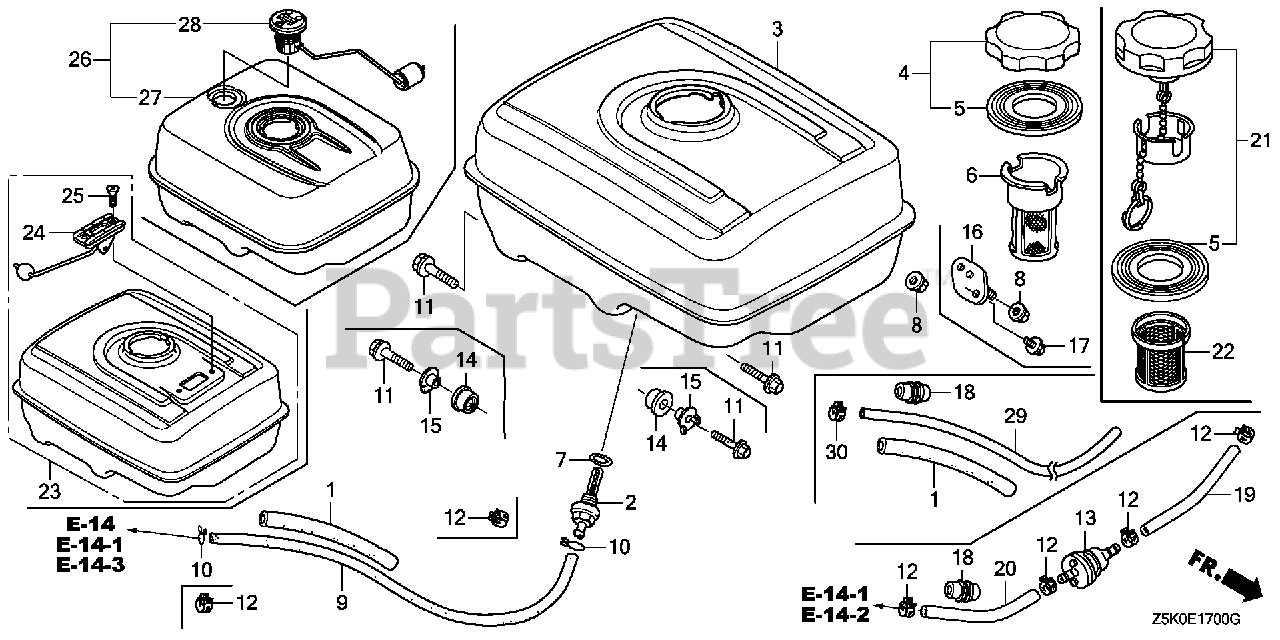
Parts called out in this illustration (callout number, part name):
1	RUBBER, SUPPORTER (107MM)
2	JOINT, FUEL TANK
5	GASKET, FUEL FILLER CAP (39X62X3) (RADICON)
7	O-RING (13.5X1.5) (ARAI)
7	O-RING (14MM) (NOK)
8	NUT, FLANGE (8MM)
9	TUBE, FUEL (4.5X210) (FKM)
11	BOLT, FLANGE (8X25)
12	CLAMP, TUBE (D8)
21	CAP, FUEL FILLER
27	TANK, FUEL *NH31* (MCKINLEY WHITE)
